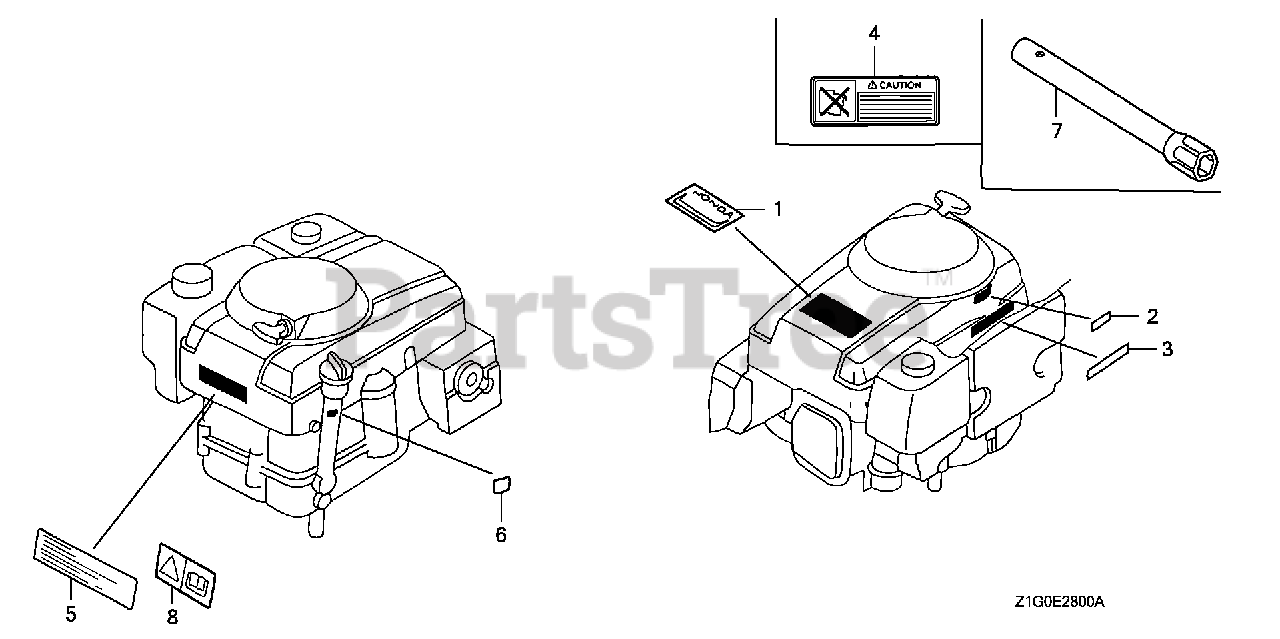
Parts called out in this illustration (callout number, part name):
1	EMBLEM, TOP COVER (13.0)
2	LABEL, FUEL CAUTION
3	LABEL, HONDA NAME
4	LABEL, MAINTENANCE CAUTION
5	LABEL, CAUTION
6	MARK, TYPE (DP23)
7	WRENCH, BOX (P21)
